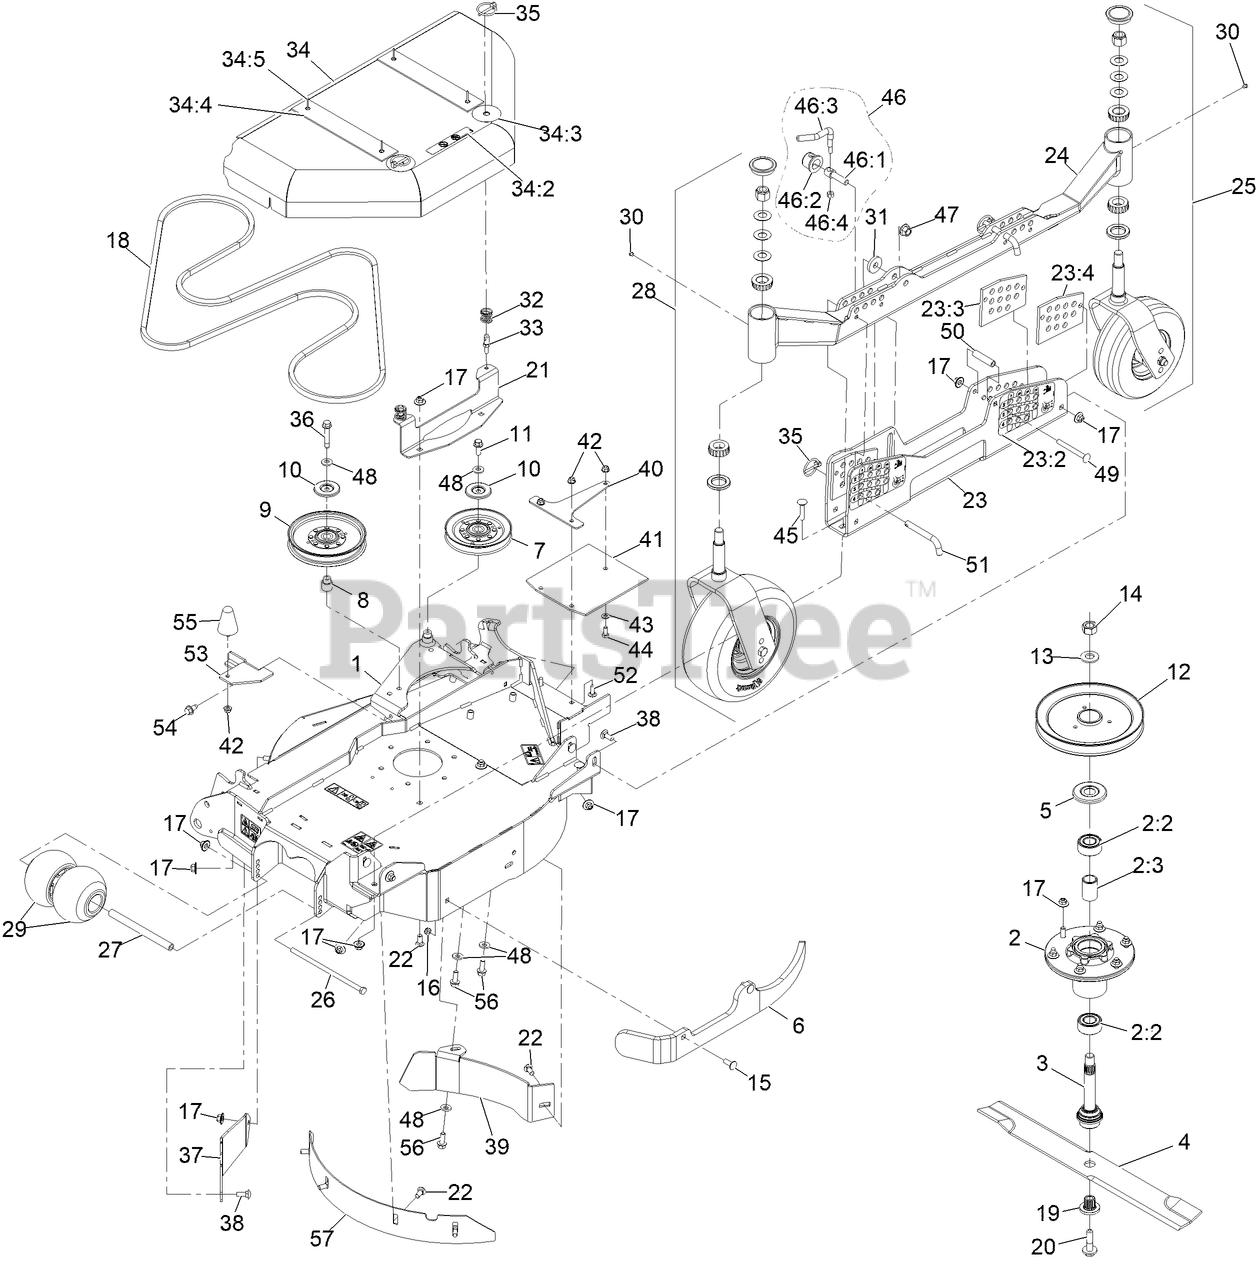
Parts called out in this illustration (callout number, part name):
1	ASM-DECK, LH WING 96
2	ASM-CUTTER HSG
2:2	BEARING-3205 TRASHGUARD
2:3	SPACER-BEARING
3	ASM-SPINDLE AND SEAL
5	GUARD-BEARING, TOP
6	BUMPER-96 LH
7	IDLER-V
8	BUSHING-IDLER
9	IDLER-PULLEY
10	SHIELD-DUST
11	SCREW-HHF 3/8-16 X 1
12	SHEAVE-SINGLE 96RD
14	NUT-HEX
15	SCREW-CARR
17	Nut-Nyloc 3/8-16 Flg
19	BUSHING,SPLINED
20	SCREW,SEMS 1/2-20 X 2.19
21	BRACKET-SHIELD MOUNT, OUT
22	BOLT-CARR
23	LH HOC CHANNEL ASM
23:2	DECAL-HEIGHT OF CUT-LH
23:3	PLATE-GUIDE, HOC (LH)
23:4	PLATE-GUIDE, HOC (RH)
24	TUBE-HOC, LH
25	Caster/Wheel ASM
26	SCREW-HH
27	SPACER-WHEEL
29	ROLLER-SCALP, ANTI
33	PIN, SPRING
34	ASM-Wing Shield LH
34:2	DECAL-NO STEP
34:3	DECAL-SCRATCH COVER
34:4	Plate-Uhmw 2"
34:5	Rivet-Pop
35	PIN-LYNCH
36	SCREW-HHF
37	PLATE-FILL, LH DECK
38	BOLT-CARR
39	BAFFLE-BLOCK, LH WING
40	SUPPORT-FLAP, LH
41	GUARD-TIRE, LH
42	NUT-HF, NI
43	WASHER-PLAIN
44	SCREW-HH
45	SCREW-CARR
46	LEVER ASM
46:1	SCREW-LOCK
46:2	CAP-LOCK
46:4	NUT-LOCK, NI
47	Nut-Lock 1/2-13
48	WASHER-BELLEVILLE
49	SCREW-CARR
51	PIN-HOC
52	BOLT-CARR
53	BRACKET-COVER RETAINER
54	SCREW-HWH
55	BUMPER-RUBBER
56	SCREW-HHF
57	BAFFLE-DEPTH, LH
